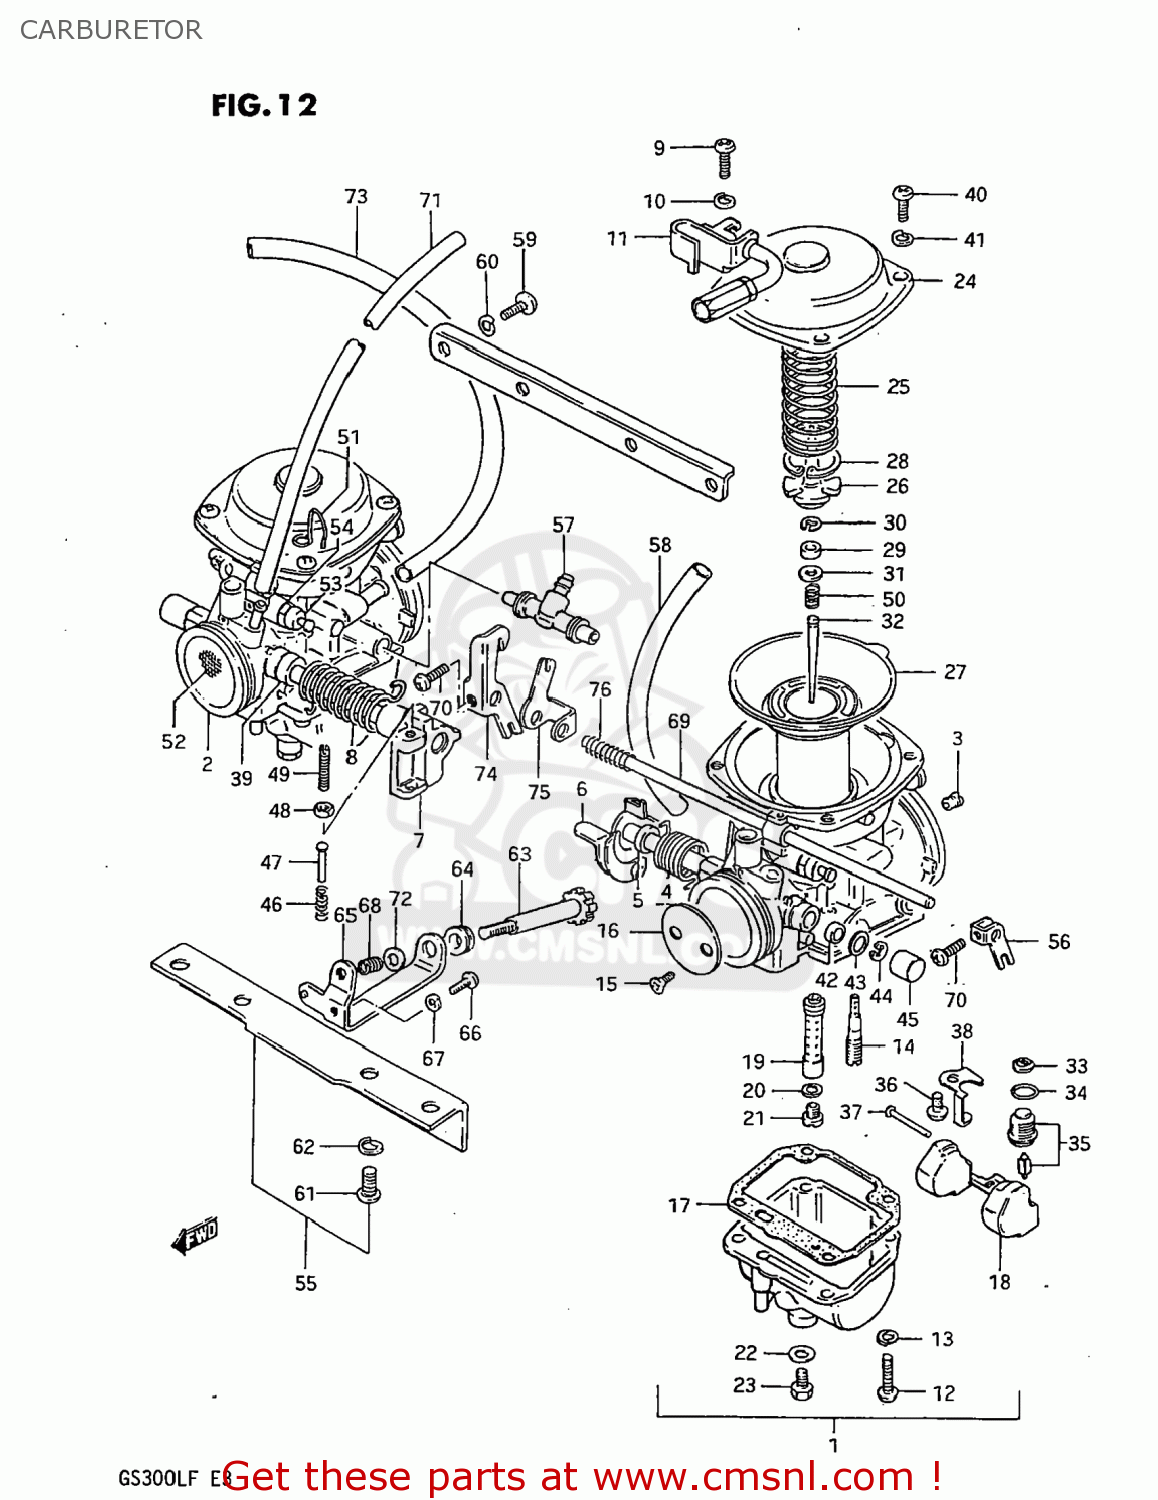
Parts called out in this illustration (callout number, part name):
1	CARBURETOR ASSEMBLY
2	CARBURETOR ASSEMBLY,RIGHT (BS
3	JET,MAIN
4	SPRING
5	RING
6	SHAFT ASSEMBLY
7	SHAFT ASSEMBLY
8	SPRING
9	SCREW
10	LOCK WASHER
11	BRACKET,THROTTLE CABLE
12	SCREW
13	LOCK WASHER
14	JET,PILOT(17.5)
15	SCREW
16	VALVE,THROTTLE
17	GASKET,FLOAT CAHMBER (NAS)
18	FLOAT
19	JET,NEEDLE
20	WASHER,NEEDLE NOZZLE
21	JET,MAIN(115)
22	GASKET (NAS)
23	PLUG,DRAIN
24	COVER,DIAPHRAGM
25	SPRING
26	HOLDER,GUIDE
27	DIAPHRAGM
28	E RING
29	RING
30	CLIP,NEEDLE
31	WASHER
32	NEEDLE JET
33	FILTER
34	O RING
35	VALVE ASSEMBLY,NEEDLE
36	SCREW 4X6
37	PIN,FLOAT
38	PLATE,NEEDLE VALVE FITING
39	RING,THROTTLE VALVE
40	SCREW
41	LOCK WASHER
42	SEAL
43	GASKET,THROTTLE SHAFT (NAS)
44	E RING
45	CAP
46	SPRING,THROTTLE SCREW
47	PIN,THROTTLE LEVER
48	NUT
49	SCREW
50	SPRING
51	CLIP,HOSE
52	FILTER NET ASSEMBLY
53	CAP,PLUNGER
54	O-RING
55	CARBURETOR ASSEMBLY
56	LEVER
57	NIPPLE,CARBURETOR
58	HOSE
59	SCREW
60	LOCK WASHER
61	SCREW
62	LOCK WASHER
63	SCREW,THROTTLE STOP
64	BUSHING,THROTTLE ADJUSTER
65	BRACKET
66	SCREW
67	LOCK WASHER
68	SPRING
69	SHAFT,STARTER
70	SCREW,THROTTLE ADJUST
71	HOSE
72	WASHER
73	HOSE
74	LEVER,STARTER
75	SPACER,STARTER LEVER
76	SPRING
